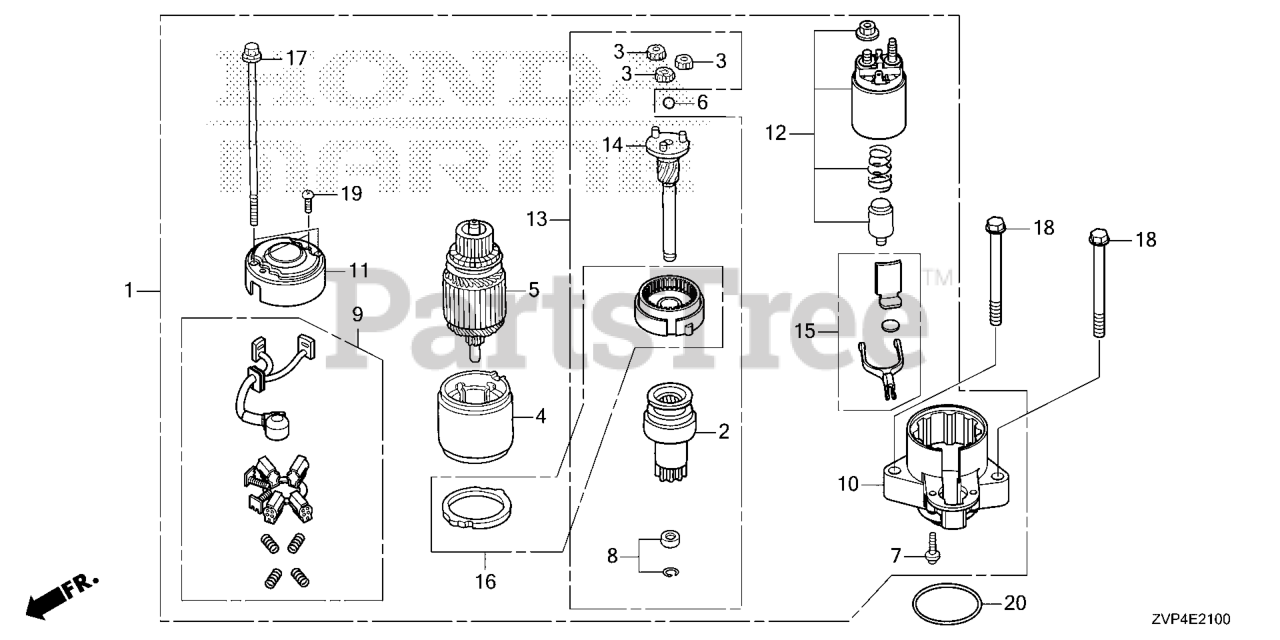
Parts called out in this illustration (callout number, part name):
1	STARTER MOTOR ASSY.
2	CLUTCH, OVERRUNNING
3	GEAR, PLANETARY
5	ROTOR COMP
6	BALL, STEEL
7	SCREW, PAN (6X22)
8	STOPPER SET, SLEEVE
9	HOLDER COMP, BRUSH
10	BRACKET, FR.
11	BRACKET, RR.
12	SW ASSY., MAG
14	SHAFT ASSY., GEAR
16	INNER GEAR ASSY.
17	THROUGH BOLT
18	BOLT, FLG (10X110)
19	SCREW, PAN (5X8)
20	O-RING (59.4X3.1)
